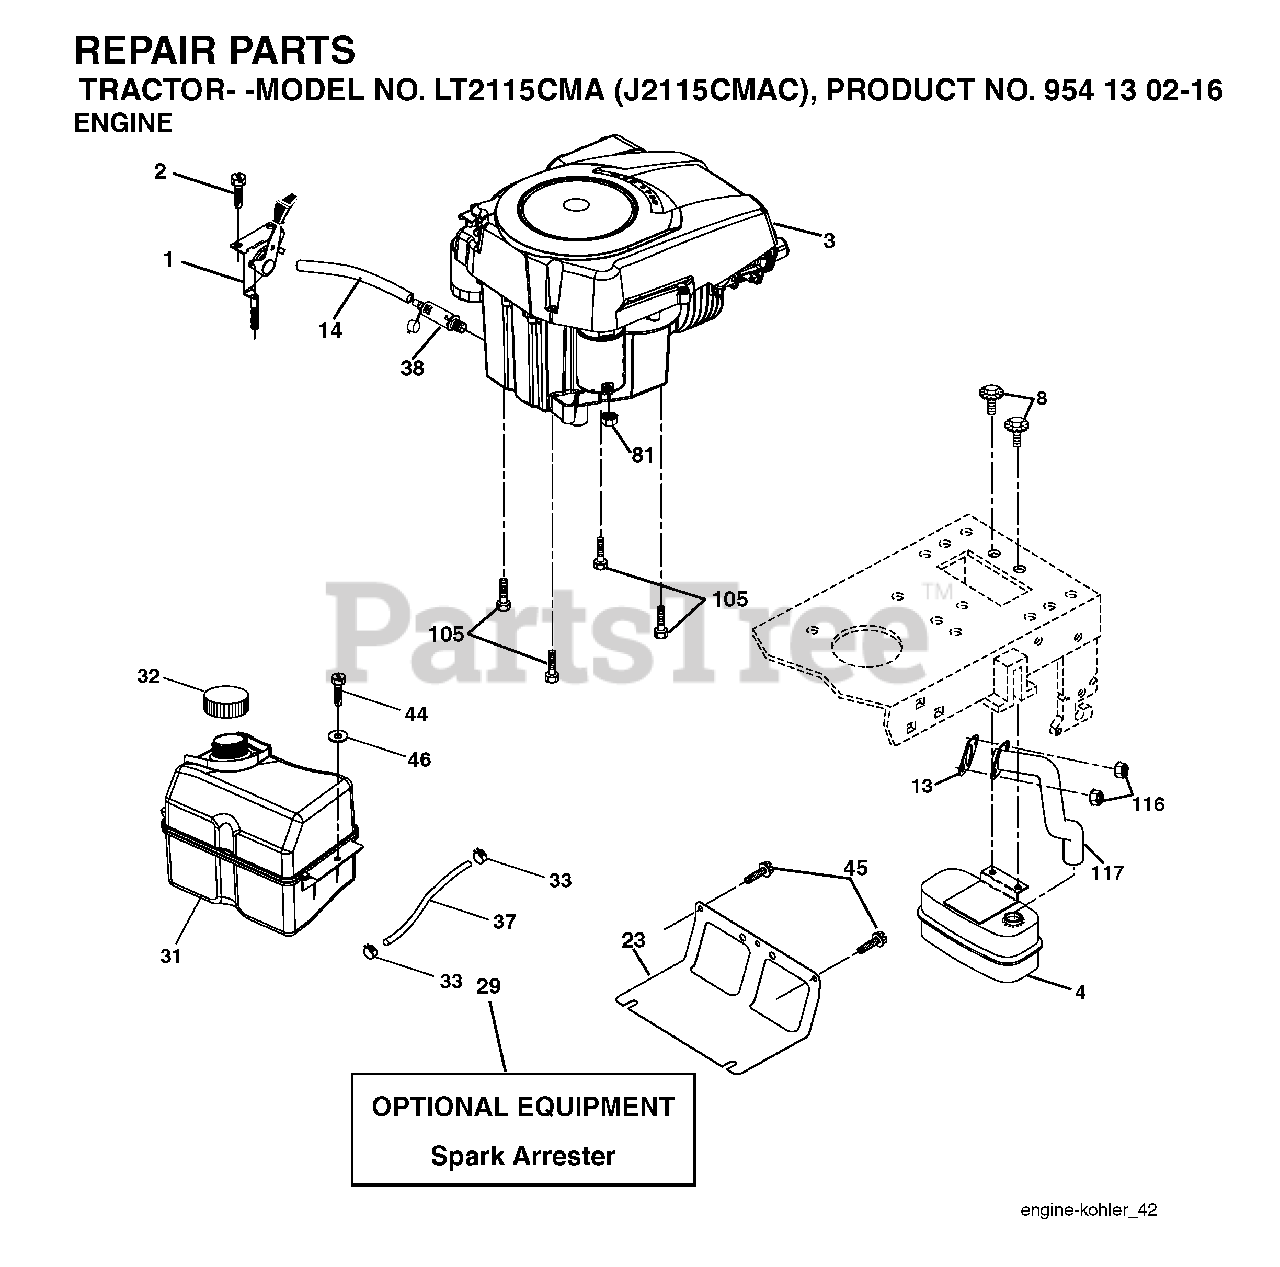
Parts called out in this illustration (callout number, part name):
1	CONTROL.THROTTLE.LT/YT
2	SCREW
4	MUFFLER.SINGLE.CYL.KOHL/B&S
8	BOLT, 5/16-18 X 1 3/4
13	GASKET ENGINE
14	TUBE, DRAIN OIL ASM.
23	SHEILD.BROWNING.DBR.GUARD
29	ARRESTER SPARK (OPTIONAL)
31	TANK FUEL
32	FUEL CAP
33	HOSE CLAMP
37	LINE.FUEL.20
38	PLUG DRAIN OIL EASY
44	SCREW HEXWSHR 1/4-20X3/4
45	SCREW, 3/8-16X3/4
46	WASHER
81	NUT
105	SCREW 3/8-16X1
116	NUT.HEX.FLANGE.TOPLOCK
117	TUBE EXHAUST
